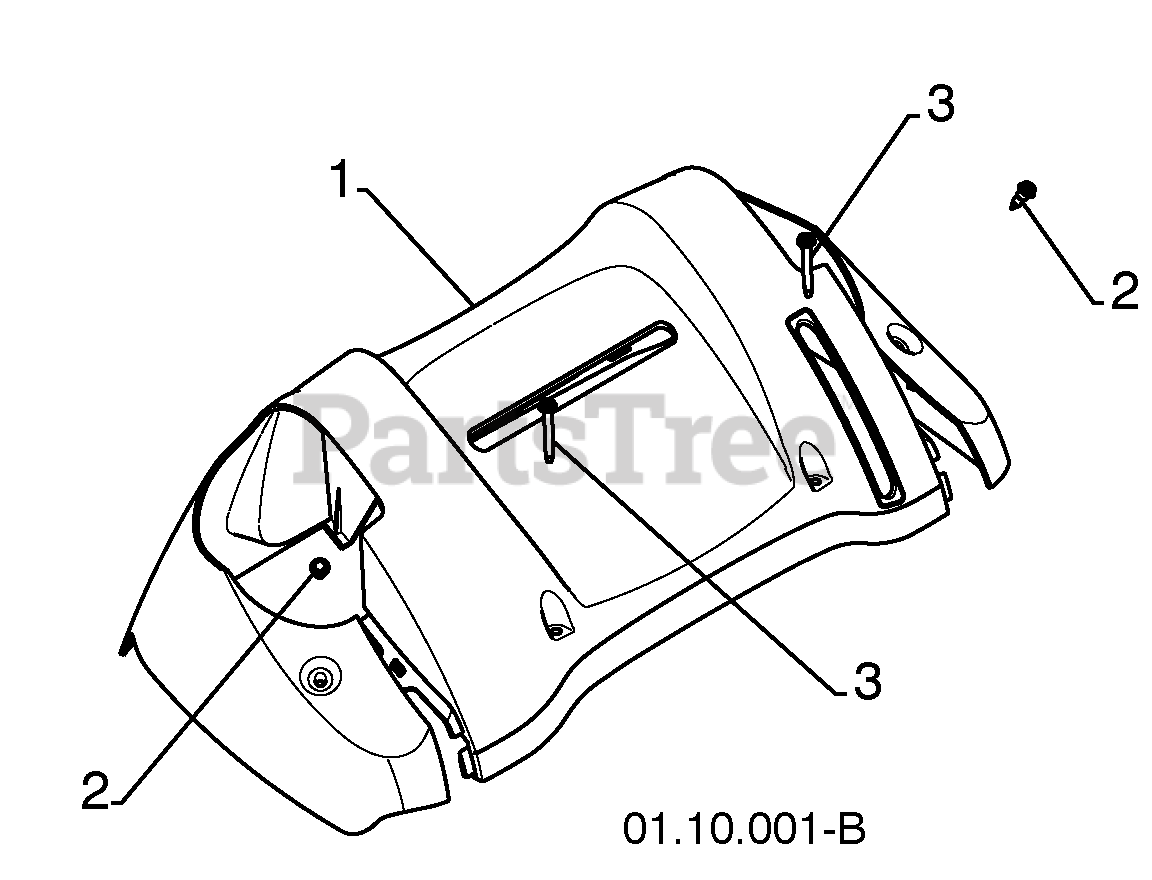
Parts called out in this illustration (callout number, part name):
1	CONSOLE PANEL
2	SCREW 10-24 X .625
3	SCREW 10-24 X 1.25
